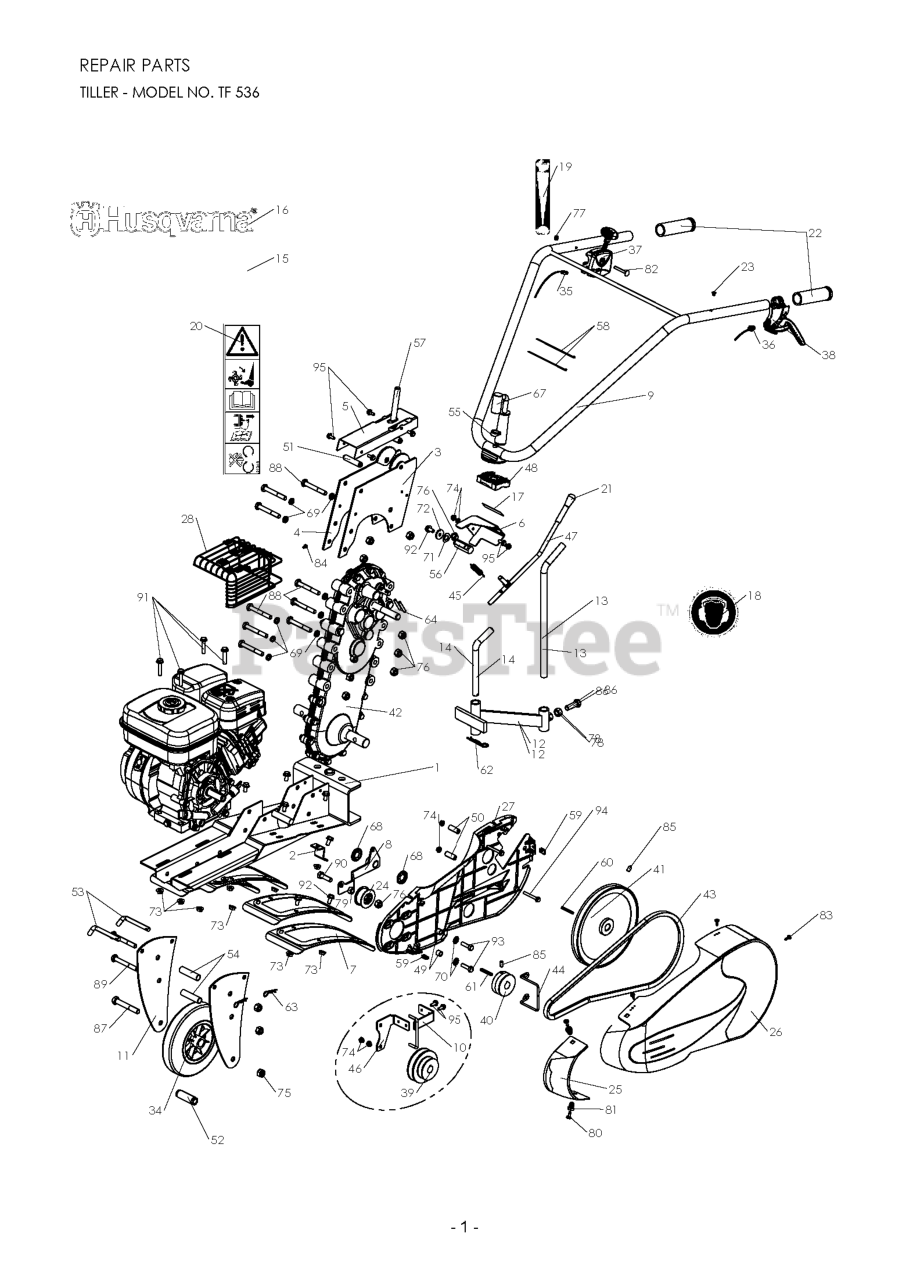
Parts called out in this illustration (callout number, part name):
45	SPRING LOCKING
63	COTTER PIN
77	Blocking nut M 6 Z
78	NUT 0300201202
93	SCREW 0300010807
